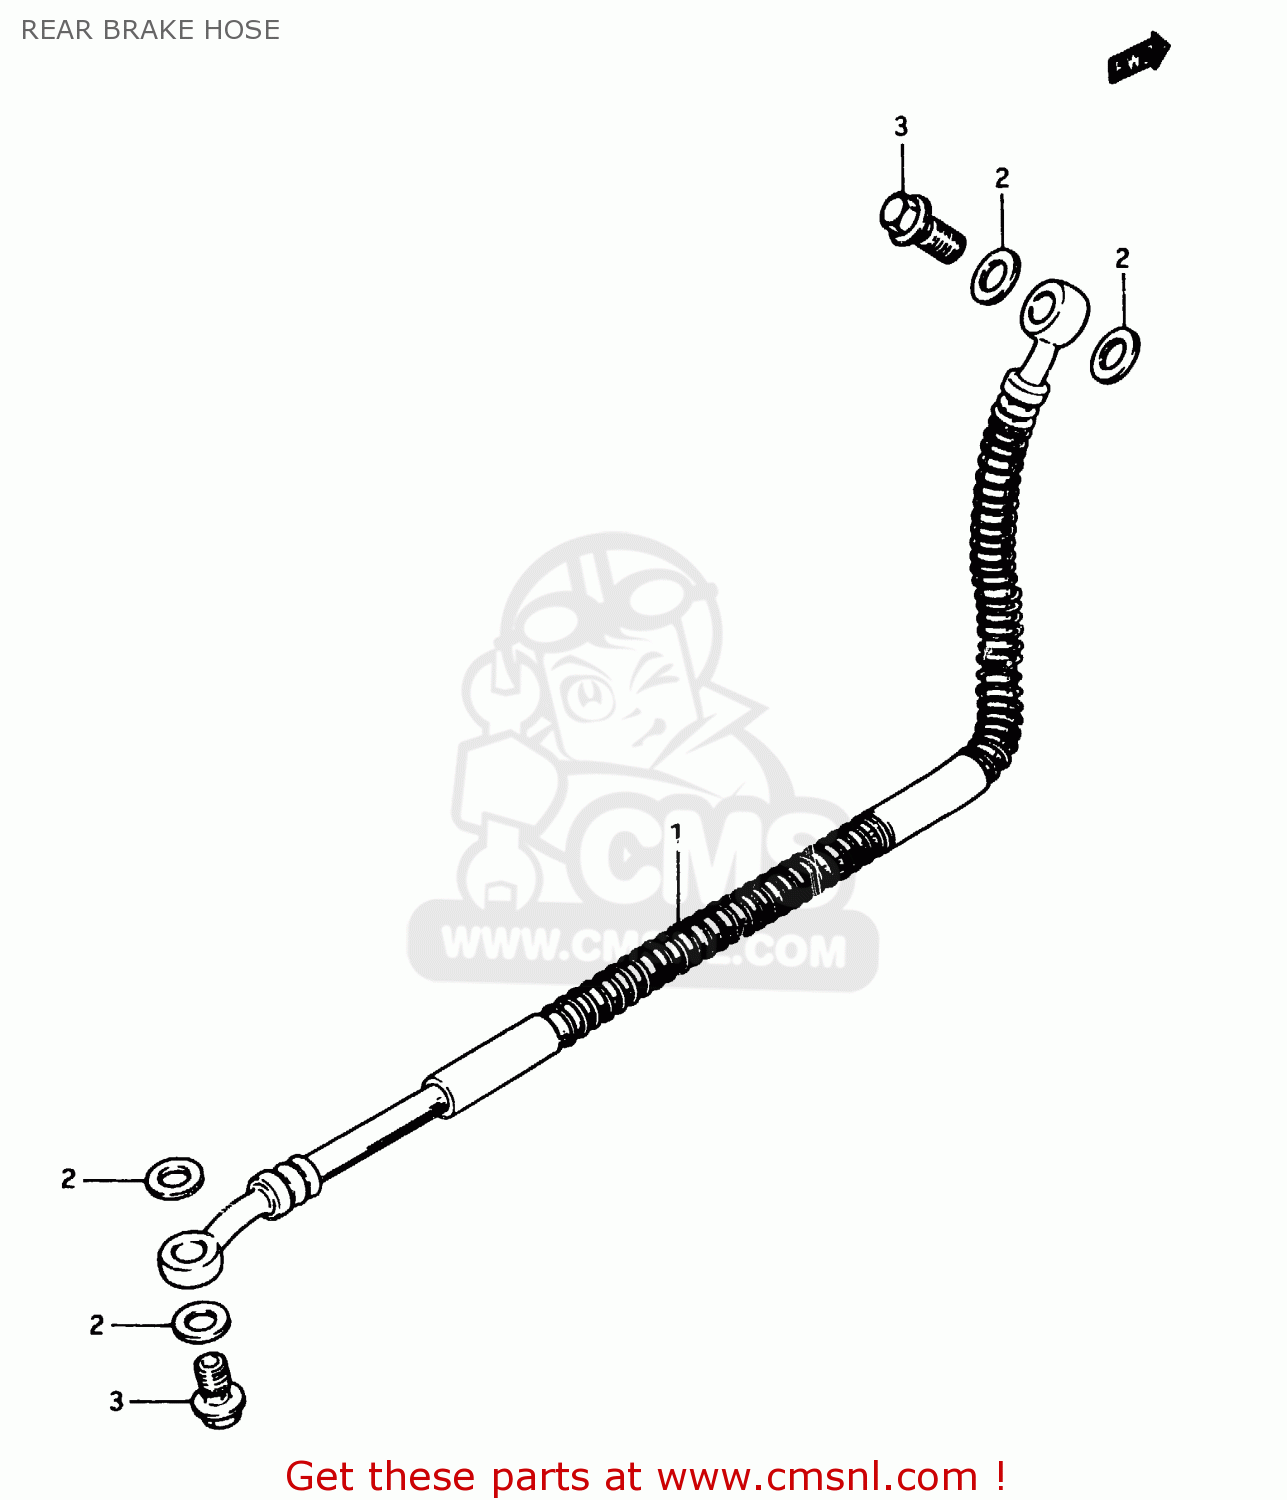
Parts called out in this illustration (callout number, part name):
1	HOSE,REAR BRAKE
2	WASHER
3	BOLT UNION
